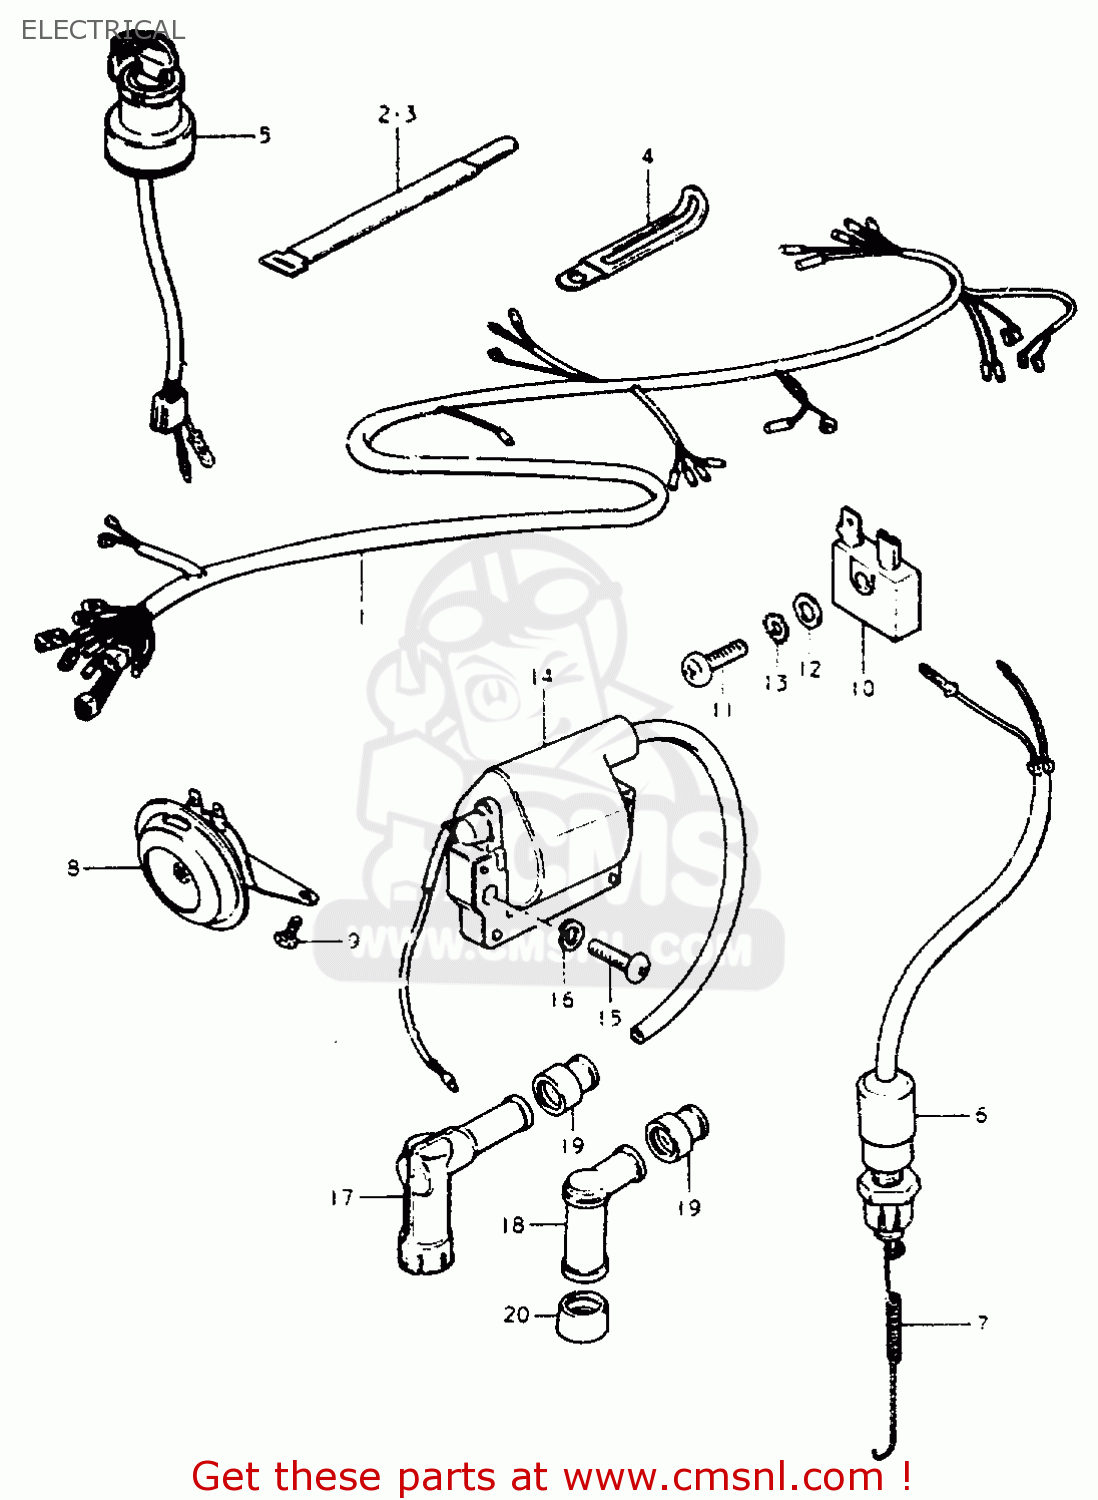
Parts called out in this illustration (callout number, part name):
1	WIRING HARNESS
2	CLAMP
3	CLAMP L:110
4	CLAMP
5	SWITCH, IGNITION
6	SWITCH ASSEMBLY,STOP LAMP
7	SPRING
8	HORN ASSEMBLY
9	BOLT
10	RECTIFIER ASSEMBLY
11	SCREW 5X20
12	WASHER
13	WASHER,LOCK
14	COIL ASSEMBLY,IGNITION
15	SCREW
16	LOCK WASHER
17	CAP,SPARK PLUG
19	SEAL,SPARK PLU
